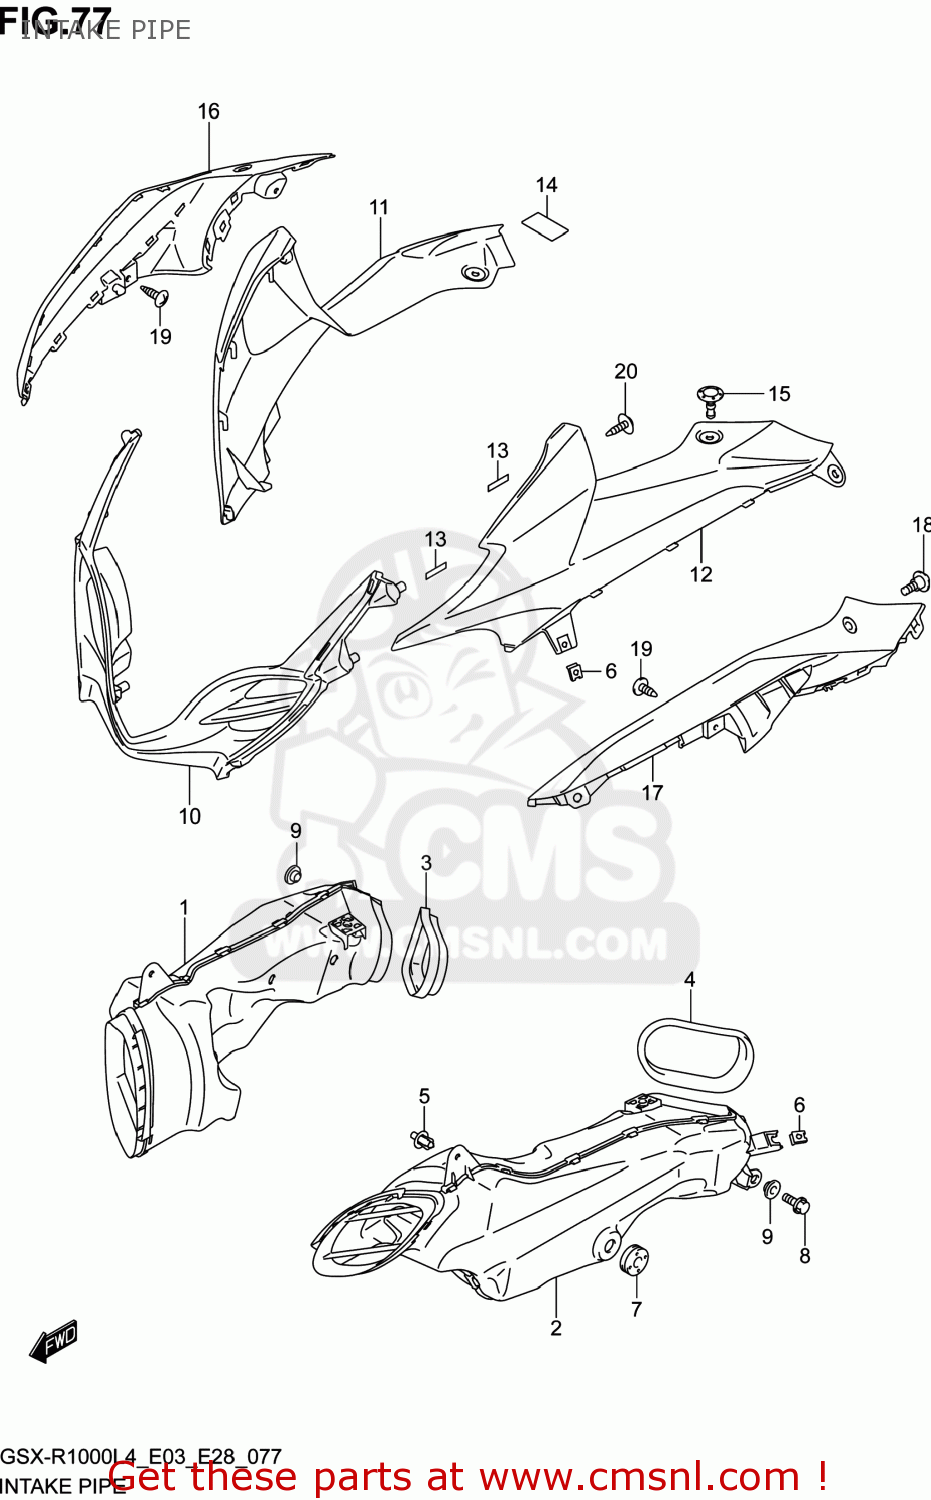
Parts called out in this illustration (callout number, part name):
1	PIPE,AIR INTAKE,R
2	PIPE,AIR INTAKE,L
3	MOLDING,AIR INTAKE,R
4	MOLDING,AIR INTAKE,L
5	CLIP(BLACK)
6	NUT
7	CUSHION
8	BOLT(6X16)
9	WASHER
10	COVER,INTAKE
11	COVER,INTAKE,R
12	COVER,INTAKE,L
13	TAPE(6X25X0.13)
14	PROTECTOR,BATTERY
15	CLIP
16	COWLING,SIDE UPR,R
17	COWLING,SIDE UPR,L
18	SCREW(5X16)
19	SCREW
20	SCREW(5X12)
